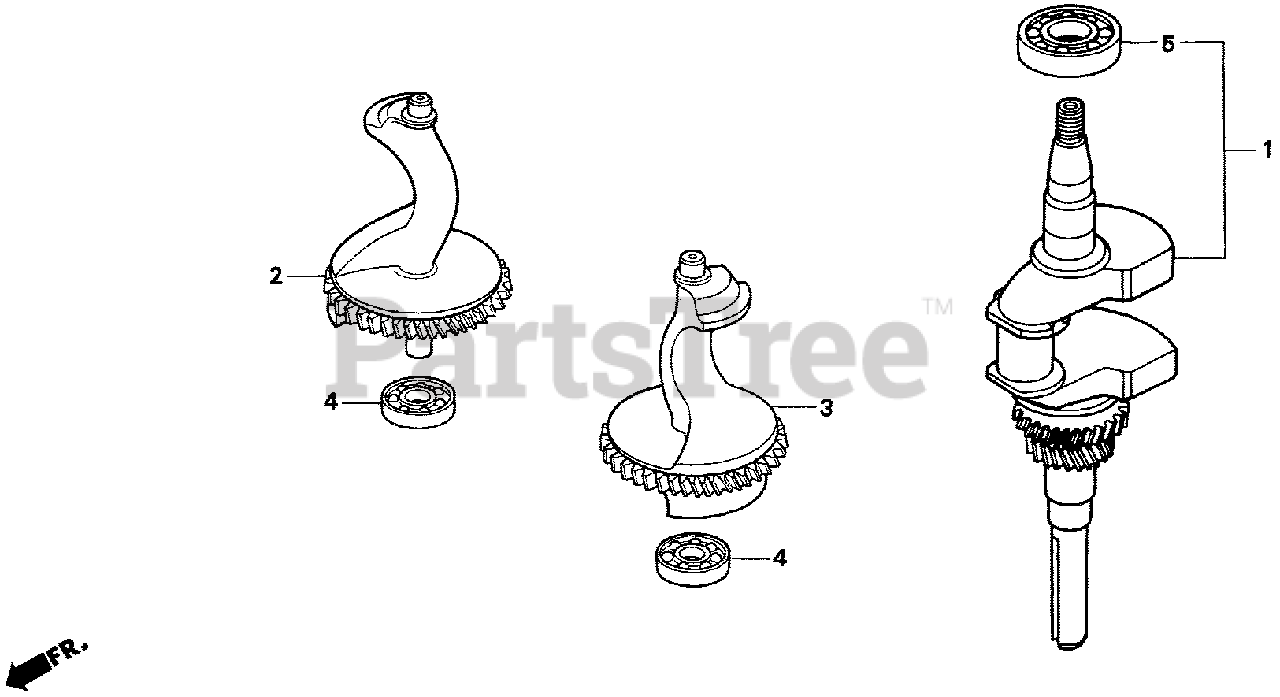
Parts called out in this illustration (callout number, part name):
1	CRANKSHAFT (Honda Code 2106185). (NOT AVAILABLE)
2	WEIGHT A, BALANCER
3	WEIGHT B, BALANCER
4	BEARING, RADIAL BALL (6202)
5	BEARING, RADIAL BALL (6206)
